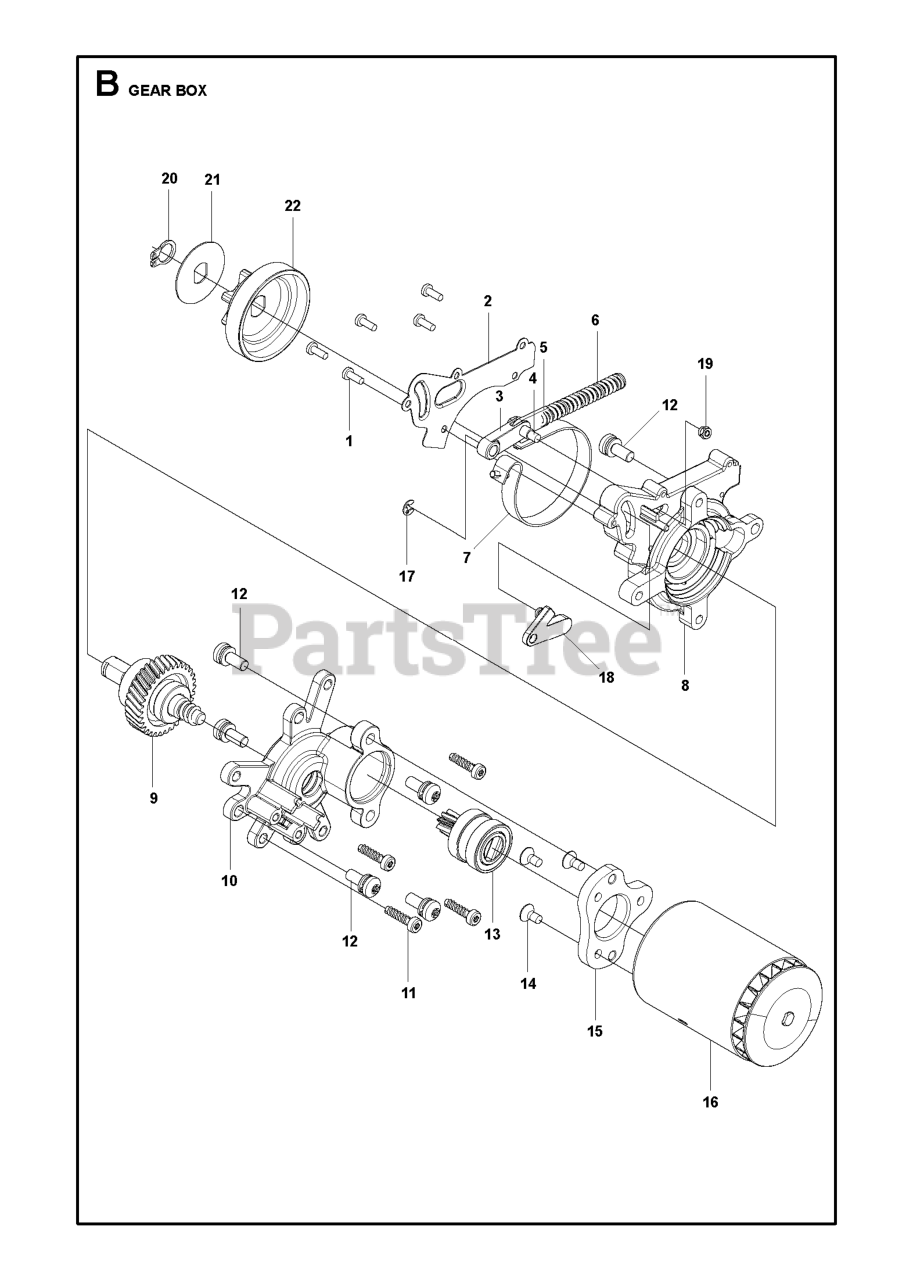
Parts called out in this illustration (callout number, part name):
1	SCREW M3X8 MACHINE SCREW
2	COVER PLATE BRAKE
3	PLATE JOINT
4	PEN BRAKE SYSTEM
5	PLATE BRAKE
6	BRAKE SPRING
7	BRAKE BAND
8	GEARBOX BOTTOM 36V
9	SHAFT ASSEMBLY
10	GEARBOX TOP
11	SCREW ST4X16
12	SCREW M5X13TOR X MACHINING SCR
13	PINION ASSEMBLY
14	SCREW SUNK M4X8
15	CONNECTOR MOTOR
16	MOTOR BLDC
17	CLAMP FOR BRAKE SYSTEM
18	DRIVE LINK DRIVE LINK
19	NUT LOCKING NUT
22	SPROCKET CHAIN 6 TOOTH
